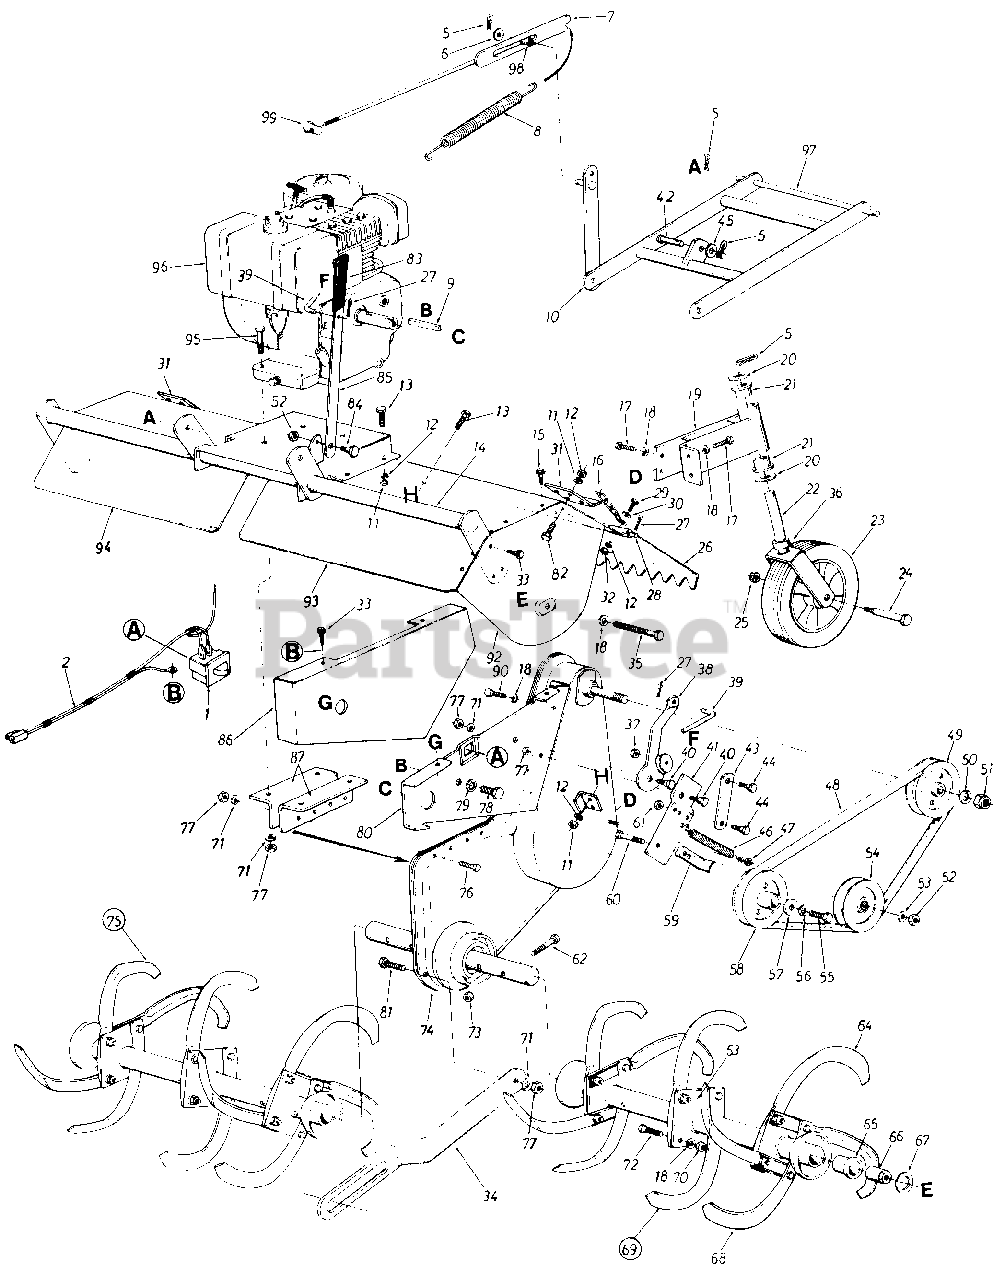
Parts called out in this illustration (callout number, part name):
1	Safety Switch
2	Wire Harness
5	Internal Cotter Pin
6	Fl-Wash. 1/2" I.D. x .93" O.D.
9	Sq. Key 1/4" x 1/4" x 2.00" Lg.
12	L-Wash. 1/4" I.D.
13	Hex Bolt 1/4-28 x .62" Lg.
16	#2 Dog Chain x 20" Lg.
17	Hex Wash. Hd. Self-Tap Scr. 318-24 x .75" Lg.
18	L-Wash. 3/8" I.D.
21	Flange Bearing 3/4" I.D. x 1.00" O.D.
24	Shoulder Bolt .623" I.D. x 3.62" Lg.
25	Hex Cent. L-Nut 7/16-14 Thd.
28	L.H Flap Rod
29	Hex Bolt 1/4-20 x .62" Lg.
30	Fl-Wash. 1/4" I.D.
33	Hex Wash. Hd. Self-Tap S 1/4" x.62" Lg.
36	Spacer .752" I.D. x 1.25" O.D.
37	Hex Cent. L-Nut 5/16-18 T
40	Shoulder Bolt 7/16" Dia. x 1.75" Lg.
45	Fl-Wash. .50" I.D. x 1.0" O.D. x .06
46	Extension Spring .62" O.D. x6.12" Lg.
47	Hex Crown Nut 3/8-24 Thd.
48	"V"-Belt (Kevlar)
49	1/2" "V"-Pulley 4.75" O.D. x .625" Bore
50	L-Wash. 5/8" I.D.
51	Hex Ins. L-Nut 5/8-18 Thd.
52	Hex Cent. L-Nut 3/8-16 Thd.
53	Fl-Wash. 3/8" I.D.
54	Idler Pulley 4.0" O.D.
55	Hex Bolt
56	L-Wash. 7/16" I.D.
57	Fl-Wash. 7/16" I.D. x 1.38"
58	1/2" "V"-Pulley .475" O.D. x 1.00" Bore
61	Hex Cent. L-Nut 5/16-18 Thd.
62	Hex Bolt 7/16-14 x 2.00" Lg.
66	Spacer
67	Thrust Wash. 1/2" I.D. x 1.55"
71	L-Wash. 5/16" I.D.
72	Hex Bolt 3/8-24 x 1.5" Lg.
73	Hex Cent. L-Nut 7/16-14 Thd.
77	Hex Nut 5/16-18 Thd.
78	Hex Bolt 1/2-20 x .88" Lg. (Grade 5)
79	L-Wash. 1/2" I.D.
80	Clutch Support Bracket
81	Shld. Bolt .435 Dia. x .265 5/16-18 Thd.
82	Hex Bolt 1/4-28 x .75" Lg.
83	Plastic Grip
84	Shoulder Bolt .498 Dia. x .212 Lg.
96	8 H.P. Engine
97	Hitch Rod
98	Push Bar Sleeve .503" I.D. x.624" O.D.
99	Ferrule
